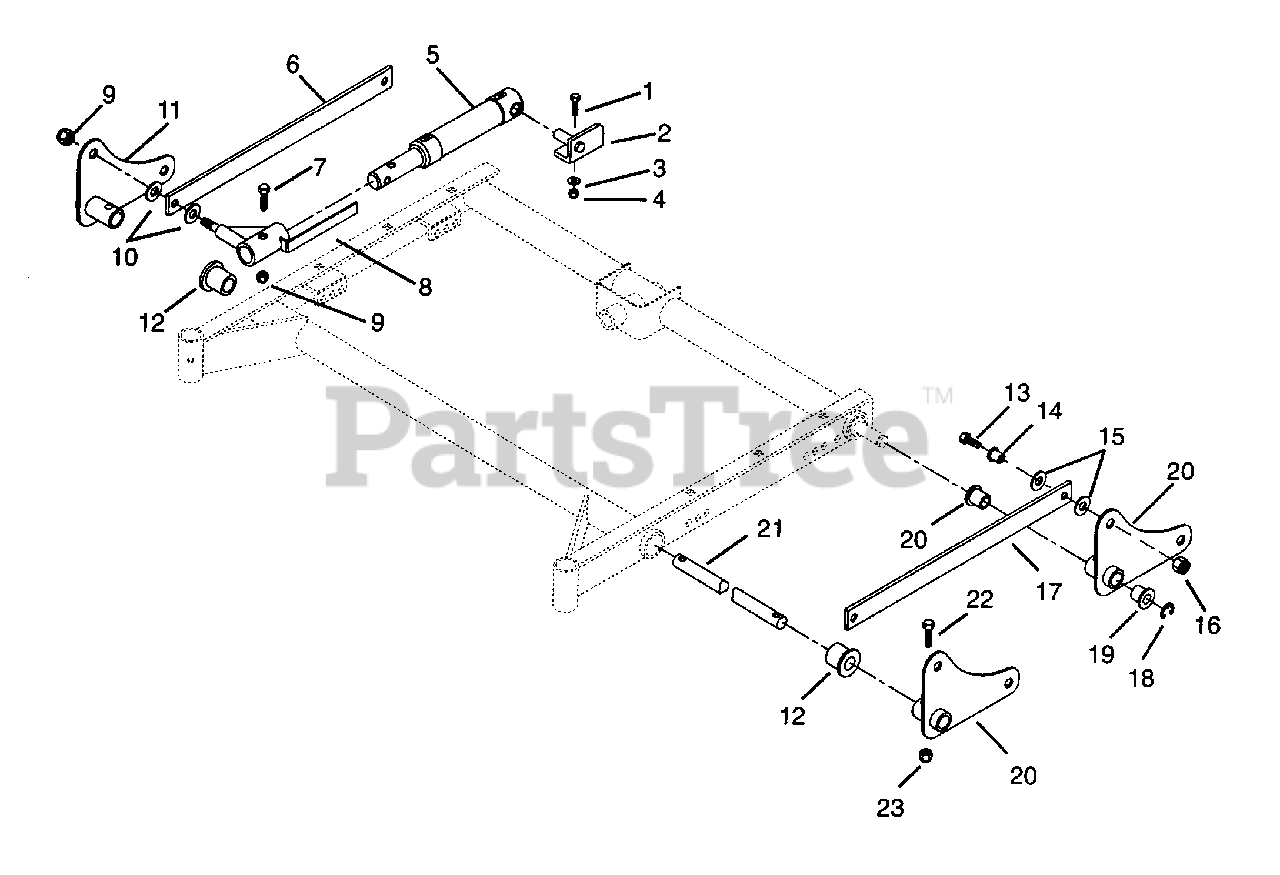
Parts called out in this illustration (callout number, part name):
1	Bolt-Hex .38-16 x 1.50 Grade 5
2	Deck Lift Rear Deck Bracket Left Hand
3	Washer-Flat-Steel .438 x 1.0 x .083
4	Nut-Locking-Nylon .375-16 Grade 2
5	Cylinder, Hydraulic
6	Link Bar, Right Hand Deck Lift
7	Bolt-Hex .50-13 x 2.00 Grade 5
8	Lift Ram Terminal Pin
9	Nut-Locking-Nylon .50-13 Grade 5
10	Washer-Flat-Steel .563 x 1.375 x .109
11	Lift Arm Weldment
12	Bushing-Flange 1.020 x 1.385 x .75 x 1.75
13	Bolt-Hex .31-18 x 1.25 Grade 5
14	Bushing-Flange .325 x .500 x .513 x .875
15	Washer-Flat-Steel .38 x .875 x .083
16	Nut-Locking-Nylon .312-18 Grade 2
17	Link Bar - Deck Lift
18	Seal 1.250 x 1.979
19	Bushing-Flange .762 x 1.0 x .580 x 1.48
20	Lift Arm Weldment Left Hand
21	X-Shaft 50 Deck Lift
22	Bolt-Hex .31-18 x 1.75 Grade 5
23	Nut-Locking-Nylon .312-18 Grade 2
